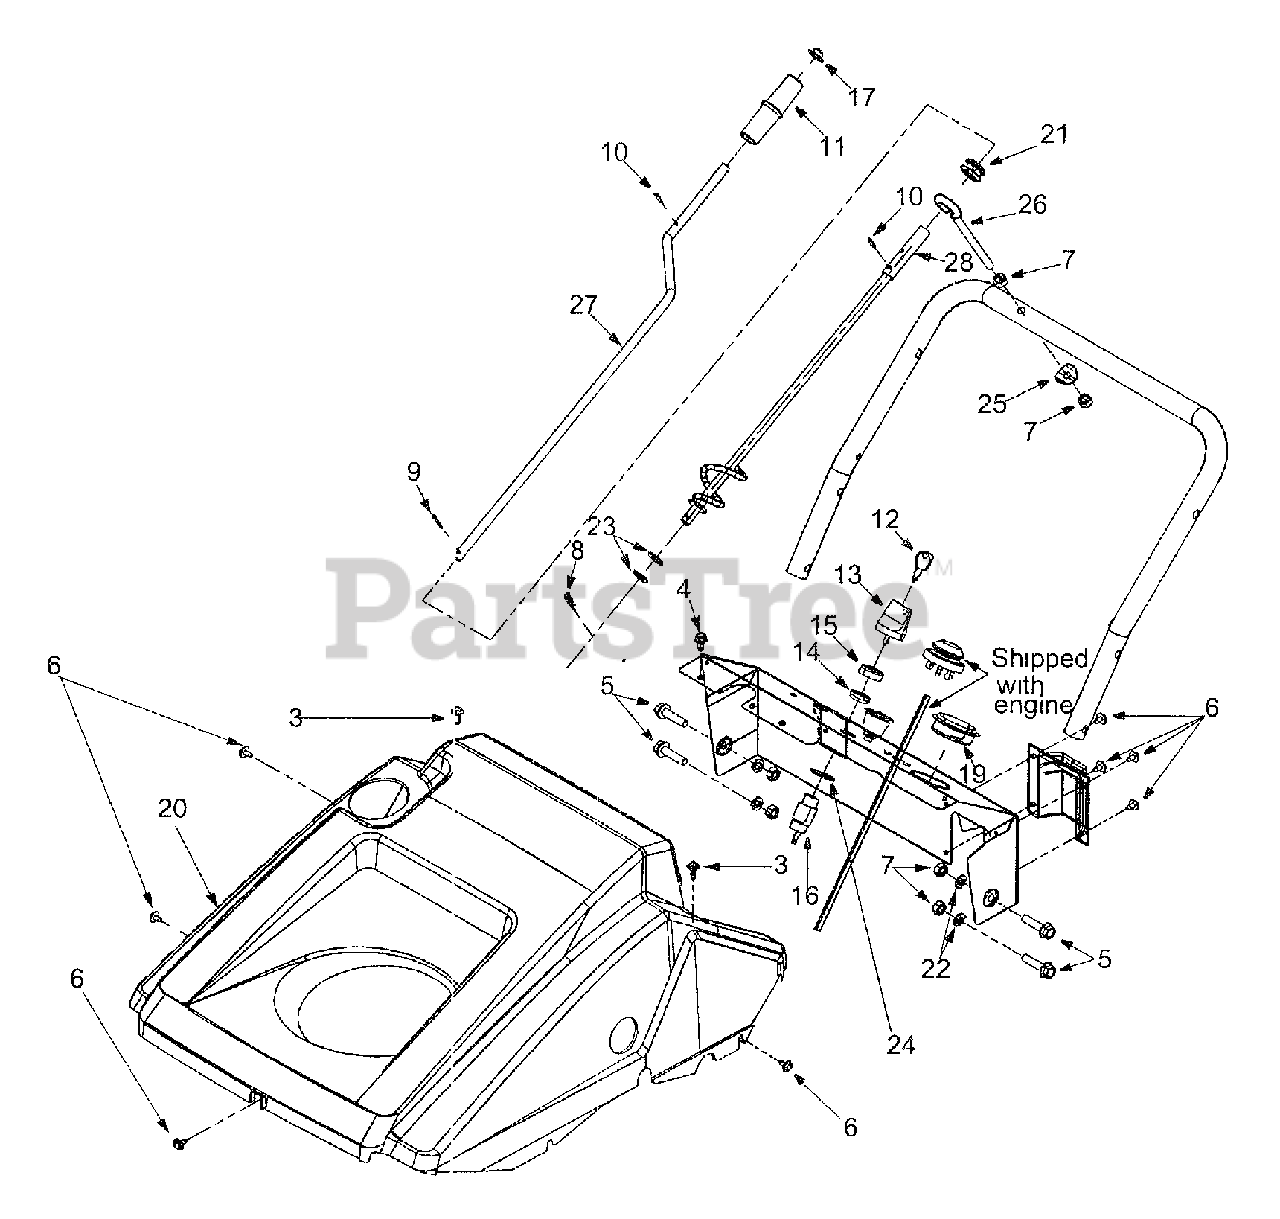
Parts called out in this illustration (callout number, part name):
1	Dash: 21" Mitten Panel Assy
2	Chute Crank Assembly
3	Special Screw
4	B Screw 1/4-14 x 0.5"
5	Hex Flange Screen,
6	Special Screw
7	Hex Nut 5/16-18
8	Cotter Pin
9	Cotter Pin
10	Roll Pin
11	Chute Crank Knob
12	Ignition Key
13	Ignition Key w/o Logo
14	Ignition Swtch Nut
15	Ignition Switch Cap
16	Switch Key Recoil Start
17	Push Cap
18	Choke Cover
20	Engine Shroud Grey
21	Rubber Grommet
22	Lock Washer
23	Flat Washer
24	Internal Lock Washer
25	Saddle Washer
26	Eye Bolt
27	Chute Crank Upper
28	Spacer
